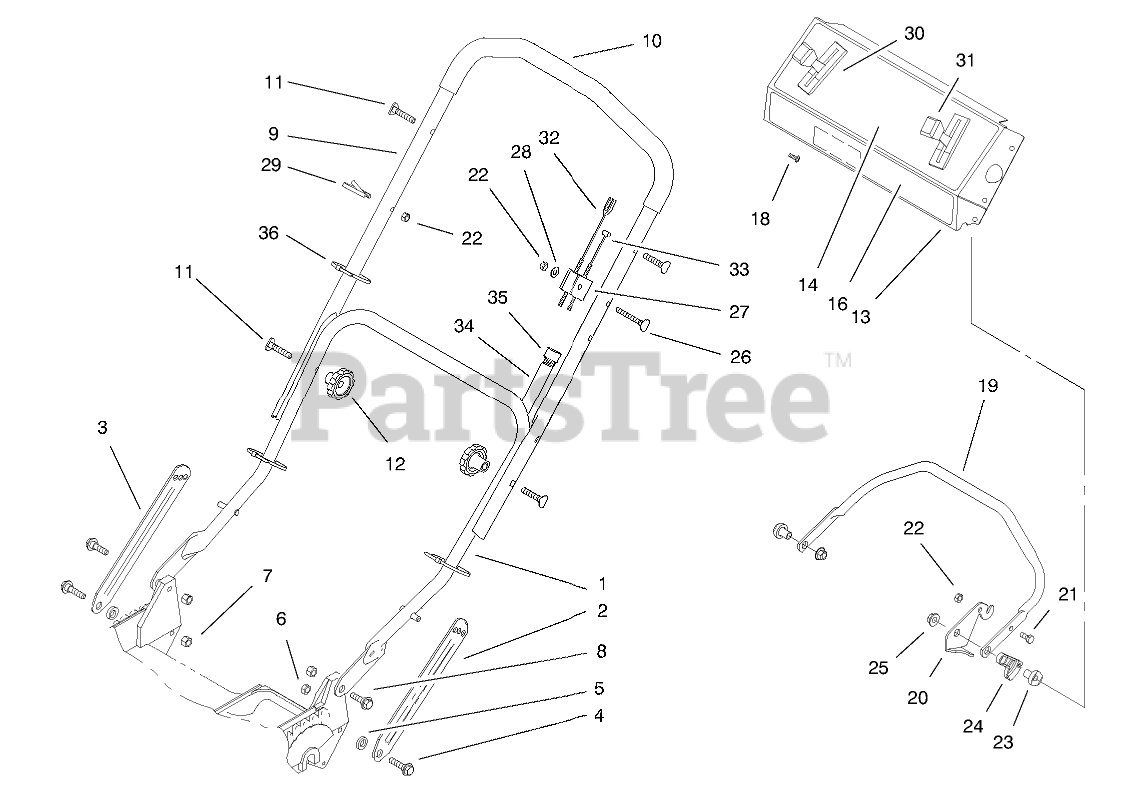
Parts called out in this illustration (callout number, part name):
1	ASM-Handle
2	Latch-Handle
3	Latch-Handle
4	SCREW-SHOULDER
5	SPACER
6	NUT-LOCK, NI
7	NUT-LOCK, NI
8	SCREW-SHOULDER
9	Handle-Upper
10	Grip-Foam
11	SCREW-HANDLE
13	Panel-Control (Incl. Ref. #14)
14	DECAL - INSTRUCTION
16	DECAL - CONSOLE
18	SCREW-TAP
19	Bar-Control
20	Lever-Control
21	SCREW-HH
22	NUT-LOCK, NI
23	SPACER-SUPPORT
24	LEVER-TRACTION
25	NUT-LOCK NI
26	SCREW-HANDLE
27	SUPPORT-CABLE
28	WASHER-FLAT
29	GUIDE-ROPE
30	CONTROL-SPEED, GROUND
31	THROTTLE CONTROL
32	BRAKE CONTROL
33	CABLE-TRACTION
34	CONTROL CABLE COVER
35	FITTING-RING
36	TIE-CABLE
